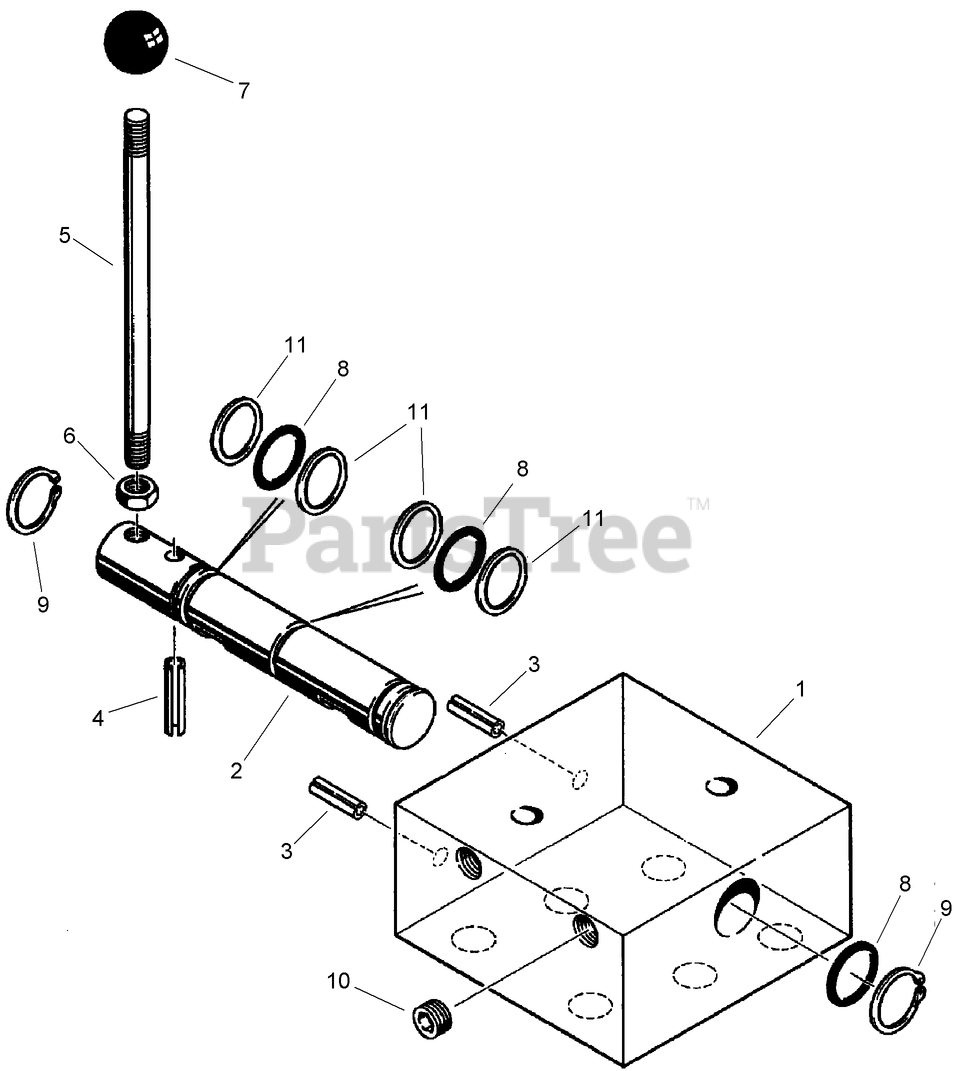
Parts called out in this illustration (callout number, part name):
1	HOUSING - Valve
2	SPOOL - valve
3	PIN - Roll, 1/4 x 1 inch
4	PIN-SPRING, SLOTTED
5	HANDLE - Valve
6	NUT-JAM
7	KNOB - Handle
8	O-RING - 11/16 ID x 7/8 inch Wide, Spool
9	RING - External Retaining, No. 87, Spool
10	PLUG
11	RING - Backup
